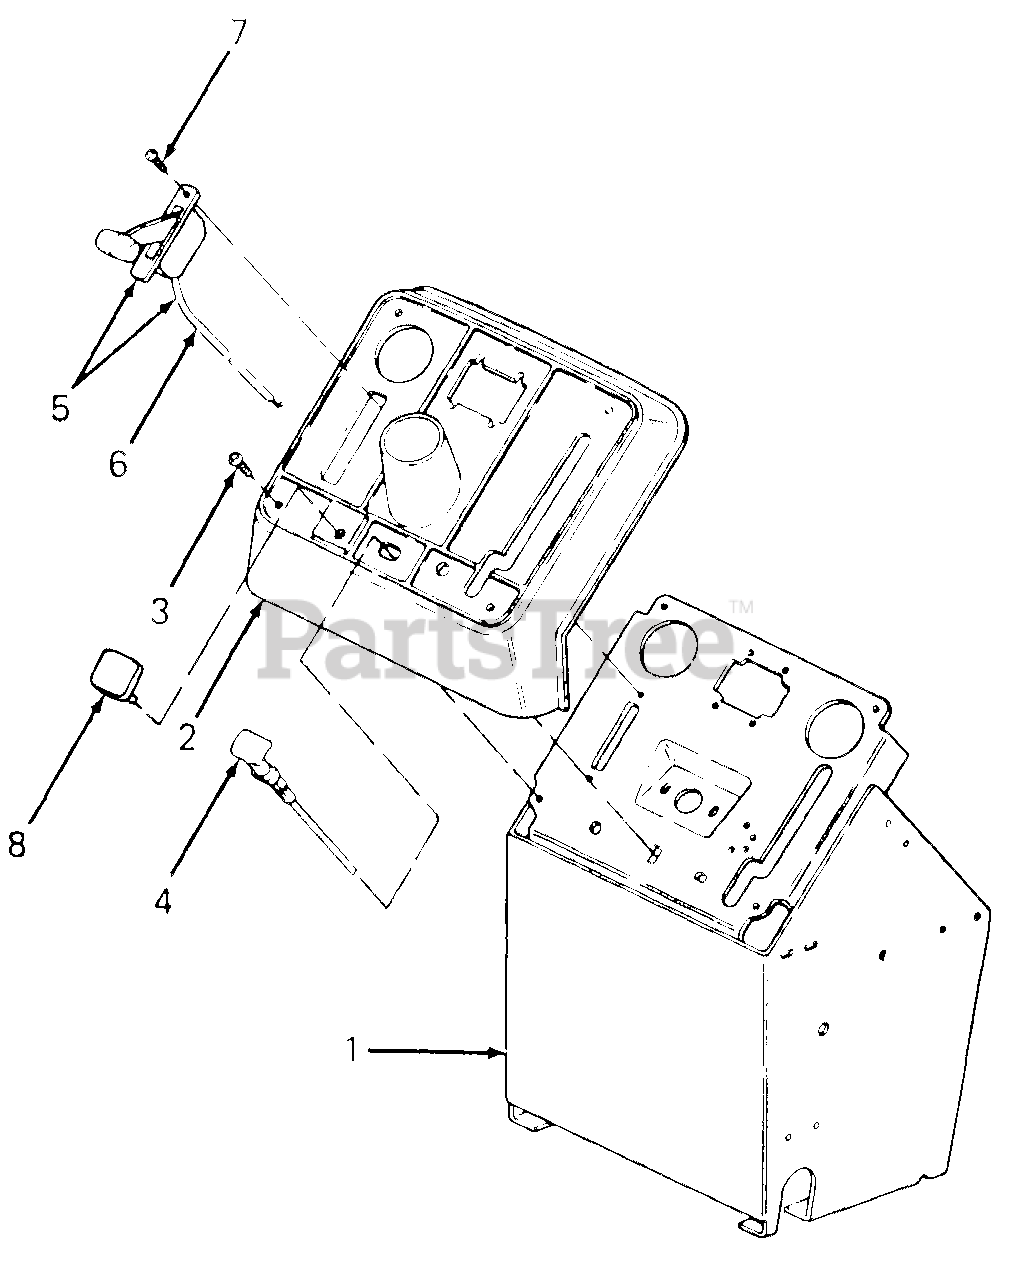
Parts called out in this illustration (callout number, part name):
2	Panel, Dash
3	Screw, Pan Hd Cutting, #10-24 X .75 Lg
4	Control, Choke
5	Control Assy, Throttle - Complete
6	Wire, Throttle Control
7	Screw, Truss Mach AB Tapp, #10 X .50 Lg
8	Plaque, PTO Cover
